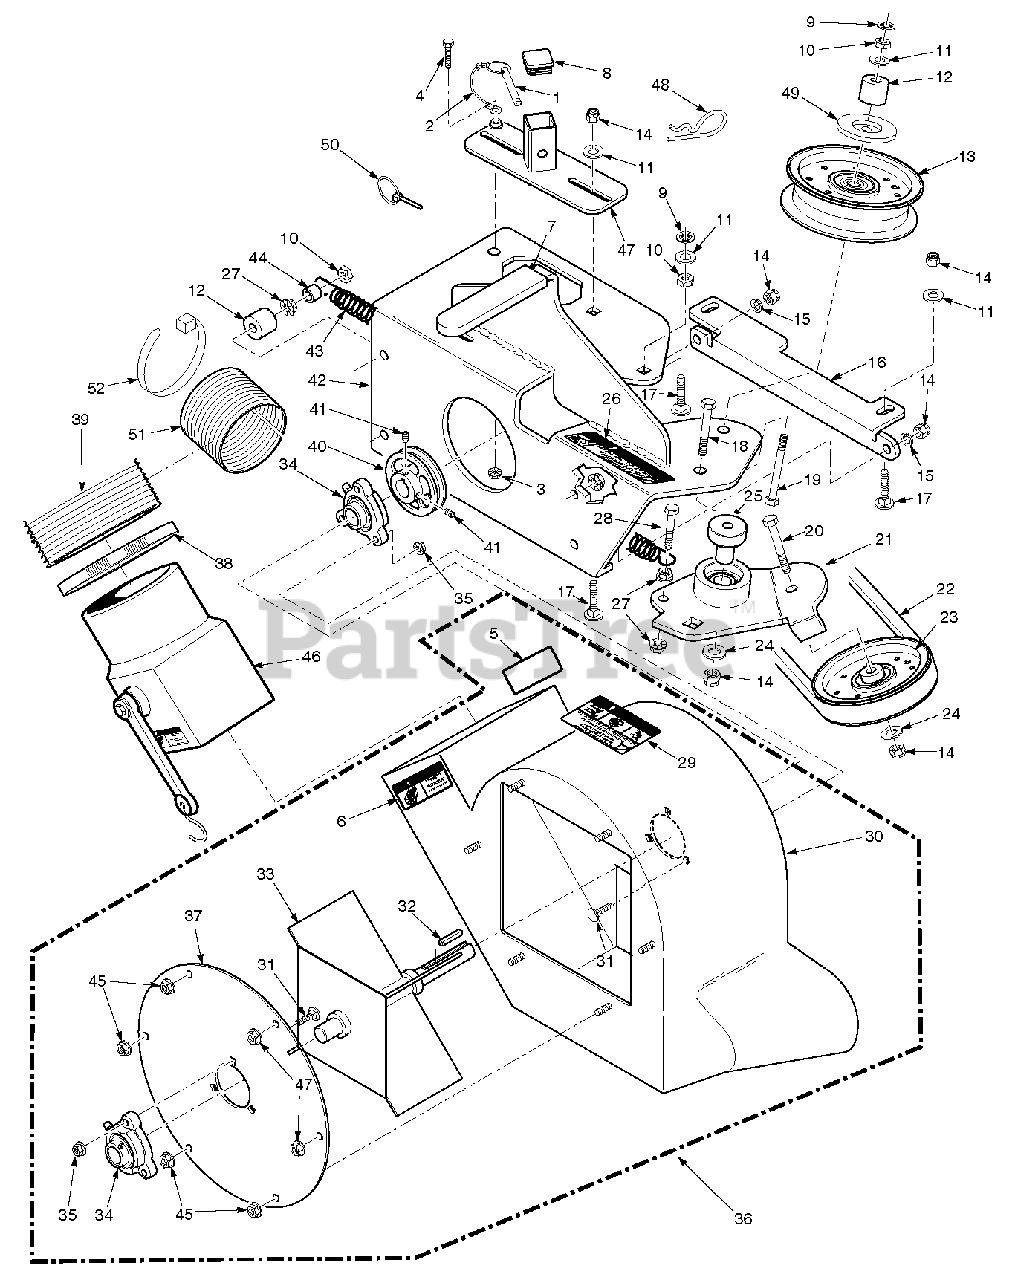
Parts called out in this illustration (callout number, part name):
1	Pin, Ring 2-1/4" Long
2	Lanyard, Deck Height Pin
3	Nut, Serr. Flange 1/4-20
4	Bolt, Hex Head 1/4-20 x 1-1/4"
5	Decal, Blower
6	Decal, Rotating Blower
7	Grip, Blower Lever
8	Cap, Square
9	Nut, Push On 3/8 Thread
10	Lock Nut, 3/8-16
11	Flatwasher, 3/8-.391 x .938 x .105
12	Spacer
13	Pulley, Idler 4" Dia.
14	Nut, Elastic Stop 3/8-16
15	Lockwasher, 3/8-16
16	Plate, Catcher Mounting
17	Bolt, Carr. 3/8-16 x 1-1/2"
18	Bolt, Hex Head 3/8-16 x 3" - 52"
19	Bolt, Hex Head 3/8-16 x 3-1/2"
20	Bolt, Hex Head 3/8-16 x 1-3/4"
21	Idler Arm Assembly
22	Belt, GC-STC
23	Pulley, 3-1/2" O.D., GC-STC
24	Washer, 3/8 Hardened
25	Pivot, Idler
26	Decal, Belt Cover
27	Nut, Serr. Flange 3/8-16
28	Bolt, Hex Head 3/8-16 x 1-1/2 Gr. 8
29	Decal, Danger
30	Blower Housing Weldment
31	Bolt, Carr. 5/16-18 x 3/4" Gr. 5
32	Key, 1/4 x 1/4 x 1-1/2"
33	Fan Weldment
34	Bearing Assembly
35	Nut, Elastic Stop 5/16-18
36	Blower Housing Assembly, GC-STT
37	Cover, Blower Housing
38	Clamp, 8-5/8" Max Dia.
39	Hose, 8.00" Dia. x 53" Long
40	Pulley, 4-3/4" O.D. - 1" Bore
41	Set Screw, 5/16-18 x 3/8"
42	Frame, Blower Mount
43	Spring, Main Drive
44	Spacer
45	Nut, Serr. Flange 5/16-18
46	Adapter w/Strap
47	Receiver Weldment, Mounting Post
48	Hair Pin Cotter, .177 x 3-1/4"
49	Dust Shield
50	Quick Pin, 5/16" Dia.
51	Hose, 8" Dia. x 24" Split
52	Cable Tie, .345 X 31.5 Black
